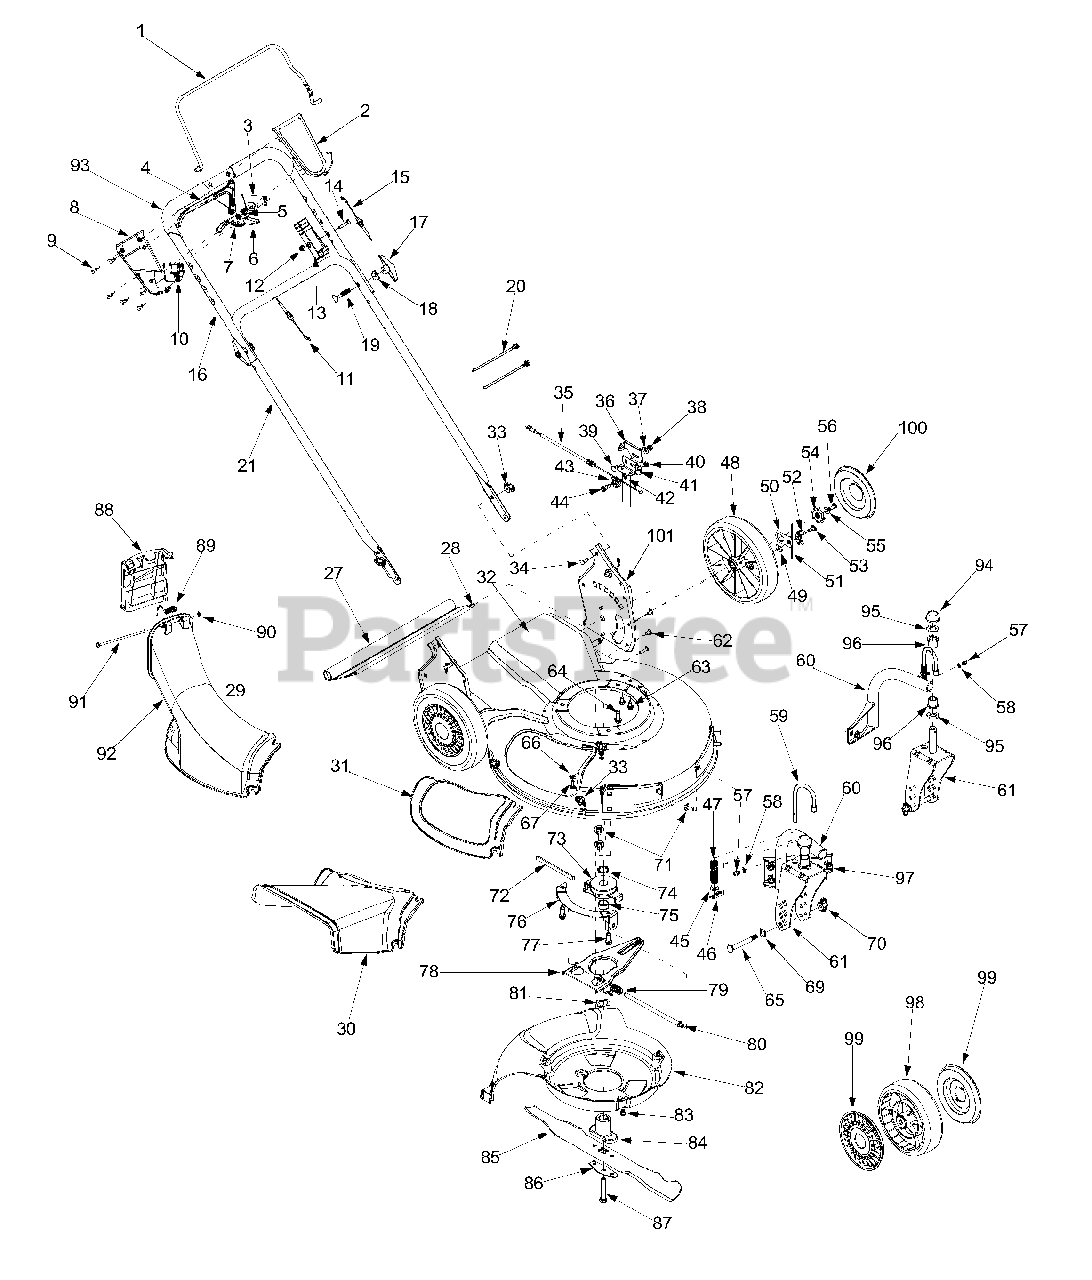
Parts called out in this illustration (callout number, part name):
1	Control Handle
2	Upper Control Handle
3	6 Spd. Rack Cable Bracket
4	Control Lever
5	Gear Insert
6	Shift Lever Spring
7	6 Speed Shift Lever
8	Lower Control Housing
9	C Sunk Tap Screw #10 x .75 Lg
10	Cable Mounting Cap
11	Drive Cable 51.0
12	Top Lock Nut 1/4-20
13	Control Housing
14	Oval C-Sunk Screw
15	Control Cable 46"
17	Wing Nut
18	Saddle Washer .320 ID x .830 OD
19	Carriage Bolt 5/16-18 x 2.0
20	Cable Tie
27	Trail Shield
28	Trail Shield Wire
29	Chute Assembly
30	Side Discharge Chute
31	Mulch Cover
33	Wing Nut
34	Carriage Bolt 1/4-20 x .75
35	6 Speed Cable
38	Hex Nut 1/4-20
39	Carriage Screw 1/4-20 x .50
40	Hex Nut 1/4-28
43	Roller Cable
44	Shoulder Screw .375 ID x 1/4-14
45	Flat Washer .330 ID x .630 OD
46	Cotter Pin
47	Compression Spring
48	Wheel 9 x 2
49	Top Lock Tab Weld Nut 1/4-20
50	Ratchet Pawl Plate
51	Plastic Spring Ratchet
53	Shld Screw .340 ID x .285 OD
54	Wheel Rachet
55	Bell Washer .265 ID x .75 OD
56	Hex Cap Screw 1/4-20 x .620
57	Grease Fitting
58	Flat Washer .203 ID x .403 OD
59	Wheel Pin Lock
60	Caster Assembly RH
61	Caster Bracket Assembly RH
62	Screw 1/4-14 x .500
63	Screw 1/4-14 x .625
64	Hex Washer Screw 3/8-16 x 1.0
65	Caster Axle
66	Flat Washer .344 ID x .62 OD
67	Carriage Screw 1/4-20 x .75
69	Wave Washer .531 ID x .781 OD
70	Wing Nut
71	Carriage Bolt 5/16-18 x .62
72	Belt 3/8 x 39.24
73	Pulley Assembly
74	Sleeve Spacer .88 ID x 1.13 OD
75	Sleeve Spacer .88 ID x 1.00 OD
77	Screw 3/8-18 x 1.0
80	Pivot Shaft
81	Wave Washer 1.38 ID x .88 OD
82	Baffle
83	Screw 1/4-20 x 3.75
84	Blade Adapter Kit
85	21" Mulching Blade
86	Blade Bell Support
87	Hex Bolt 3/8-24 x 2.5
88	Chute Door
89	Torsion Spring
91	Pivot Rod
92	Discharge Chute
93	Grip
94	Push Cap
95	Flat Washer.640 ID x 1.12 OD
96	Flange Bearing
97	Flange Lock Nut 5/16-18
98	Wheel 7 x 2
99	Hubcap - Spoke w/ Hole
100	Hubcap - Radial Spoke
